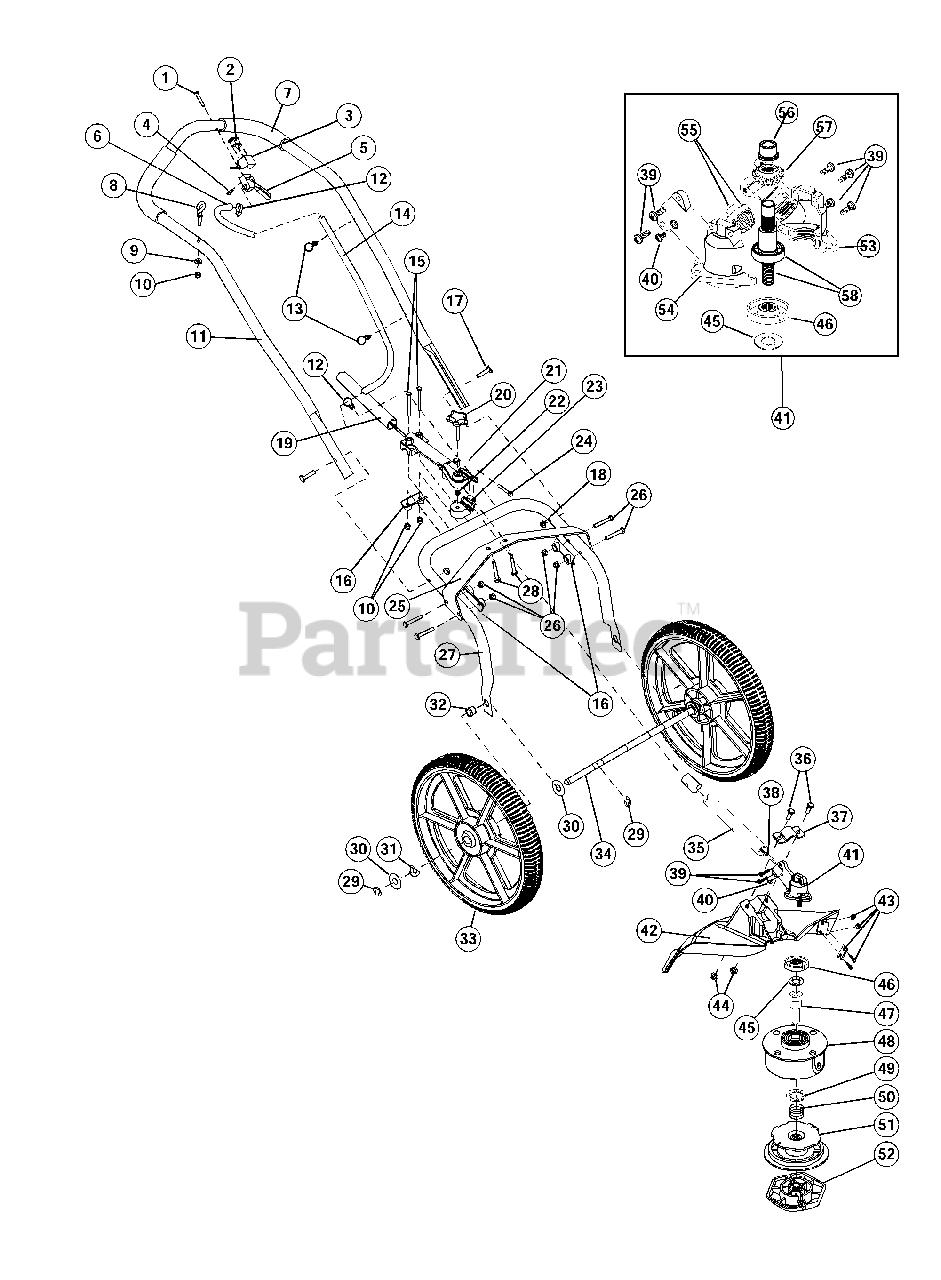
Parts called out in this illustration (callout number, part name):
1	Trigger Mount Screw
2	On/Off Switch
3	Switch Bracket
4	Weldnut
5	Throttle Trigger Assembly
6	Throttle Cable
7	Handlebar Grip
8	Rope Guide
9	Washer
10	Nut
11	Handlebar
12	Cable Tie
13	Wire Retaining Clip
14	Throttle Cable Cover
15	Hex Head Cap Screw
16	Retaining Clamp
17	Carriage Bolt
19	Upper Drive Shaft
20	Star Knob
21	Upper Clamp
22	Locknut
23	Clamp Grip
24	Bolt
25	Support Bracket
26	Hex Head Cap Screw
27	Lower Handlebar
29	E Ring
30	Washer
31	Spring Washer
32	Bushing
33	Wheel
35	Lower Drive Shaft Assembly
36	Bolt
37	Boom Mount Bracket
38	Drive Shaft
40	Anti-Rotation Screw
41	2 Piece Gearbox Assembly
43	Cutoff Blade Assembly
44	Locknut
45	Palnut
47	Spool Shaft
48	Outer Spool & Eyelet Assembly
49	Retainer
51	Inner Reel
52	Bump Knob Assembly w/Bolt
53	Left Housing
54	Right Housing
55	Pinion Gear Assembly
56	Output Shaft Bushing
57	Output Shaft Gear
58	Output Shaft Assembly
